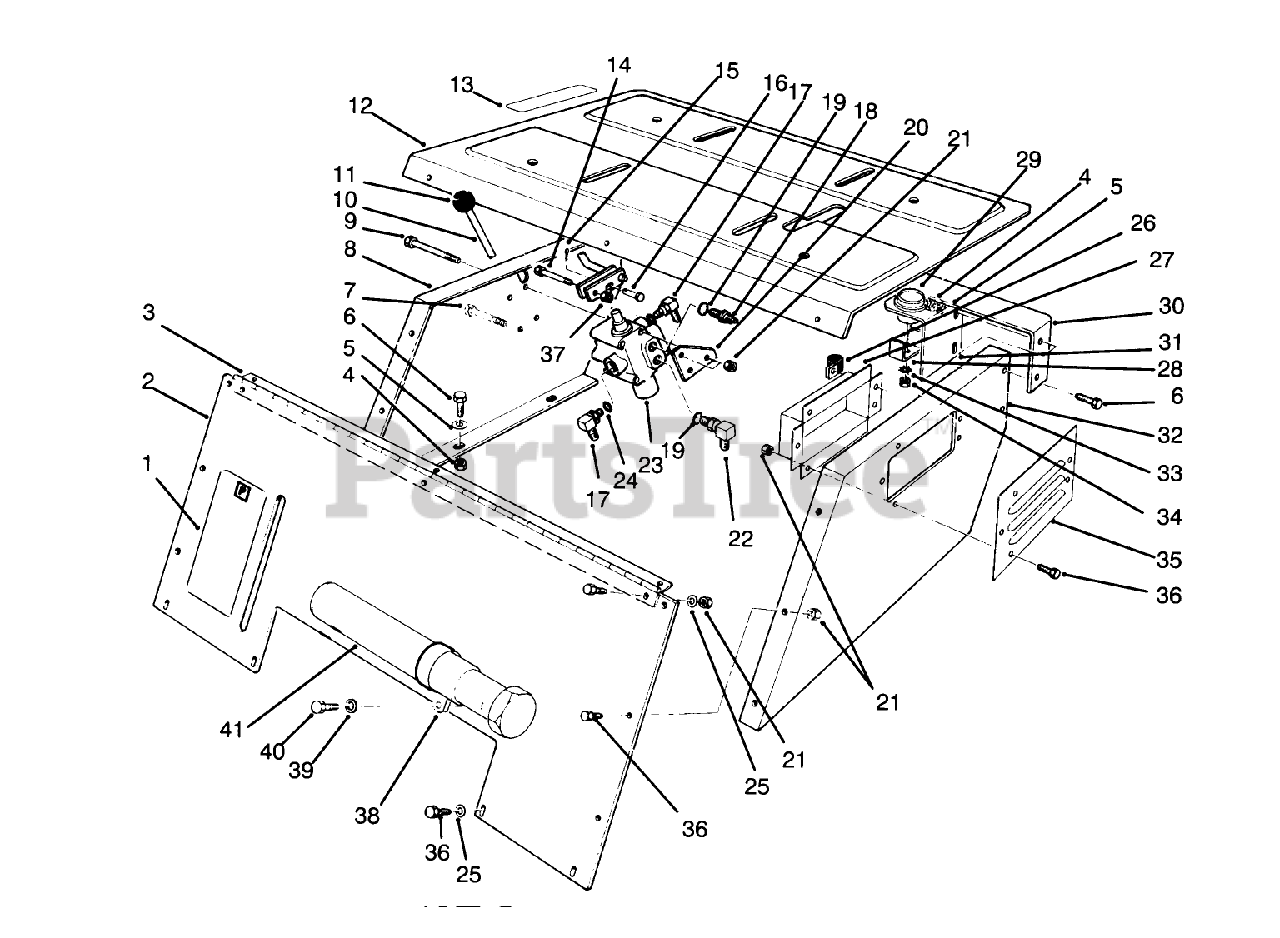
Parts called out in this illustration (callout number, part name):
1	PARK BRAKE DECAL
2	Support-Seat, Front
3	Hinge-Seat
4	NUT-LOCK, NI
5	WASHER-PLAIN
6	SCREW-HH
7	SCREW-HH
8	Support-Seat RH.
9	SCREW-HH
10	Lever-Valve
12	Plate-Seat
13	LIFT CONTROL DECAL
14	BOLT-WHEEL
15	PIN-COTTER
16	PIN-CLEVIS
17	FITTING-HYD, 90 DEG
18	FITTING-STRAIGHT
19	O-RING
20	LEVER BRACKET
21	NUT-LOCK, NI
22	FITTING-ELBOW, 90
23	VALVE ASM
24	O-RING
25	Washer-Flat
26	CLAMP
27	AIR CHAMBER WA B
28	BRACKET F/W
29	Hour Meter
30	Support-Hood
31	HR.METER BRKT. R
32	LH SEAT SUPPORT R
33	Washer-Ext. Tooth
34	NUT-HEX
35	AIR CHAMBER COVER R
36	SCREW-HH
37	NUT-LOCK, NI
38	CLAMP-R
39	WASHER-FLAT
40	SCREW-HWHTF
41	TUBE-MANUAL
